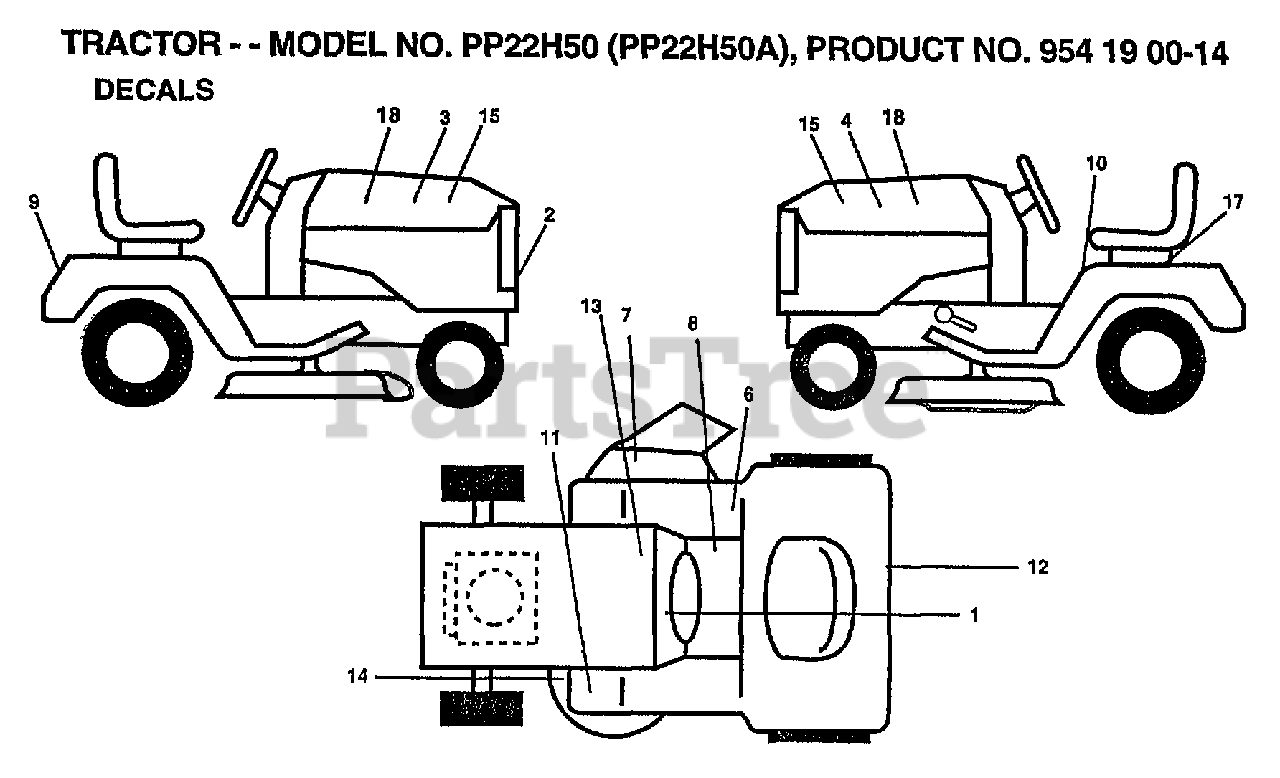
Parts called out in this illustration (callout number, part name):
1	"DECAL-INST,OPER"
2	DECAL, GRILLE
3	DECL, HOOD, RH
4	DECAL, HOOD, LH
6	DECAL, SCL COLD START HYD
7	"DECAL, WARNING"
8	DECAL BRAK PARK
9	DECAL, FENDER
10	DECAL.CAUT.ENG/FR
11	DECAL T
12	DECAL D-BAR CNTRL
13	DECAL.BATRY.3-3908
14	"DECAL.V.BELT.44"""
15	NAMEPLATE HOOD POULAN PRO
17	RETAINER-SPRING
18	DECAL DOMED
